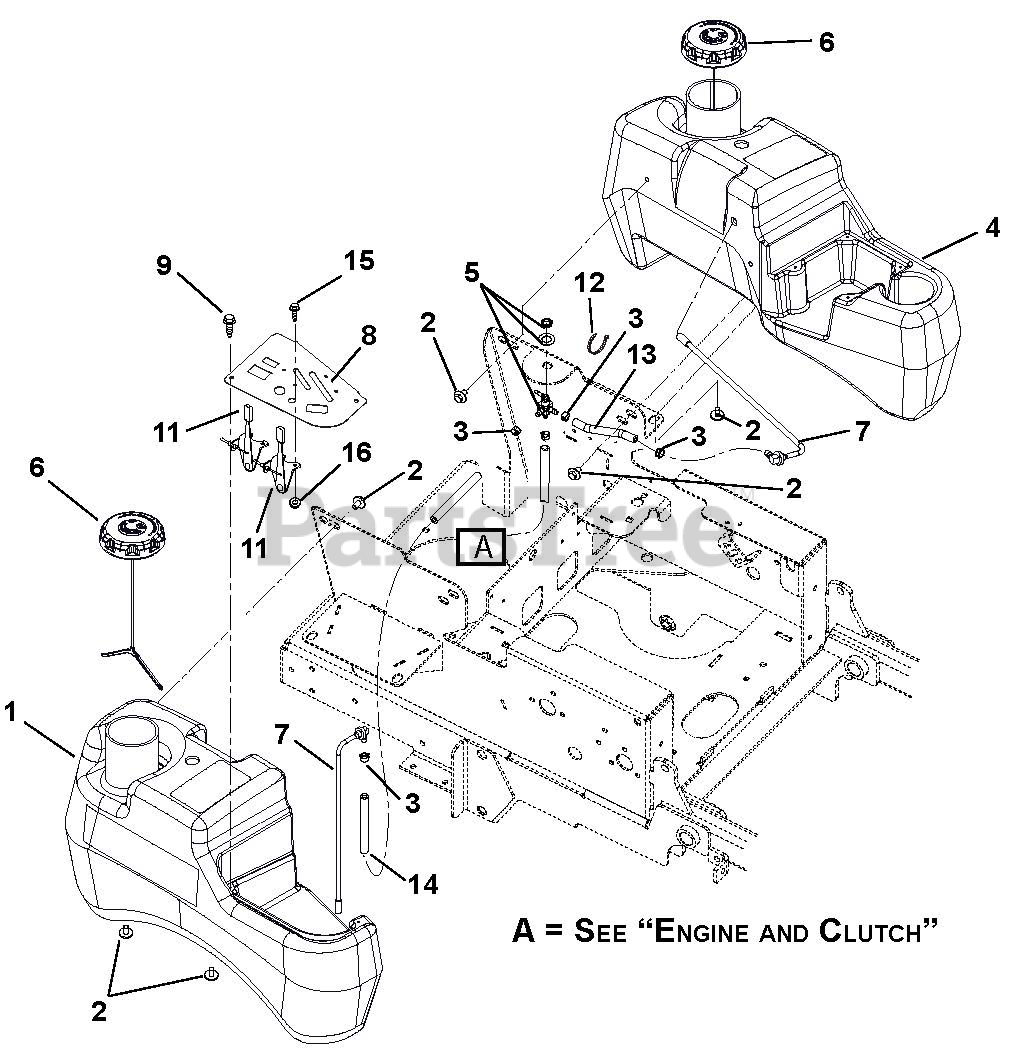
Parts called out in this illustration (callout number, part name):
1	Tank, Fuel Right Hand
2	Bolt, SEMS .31-18 x .62
3	Clamp, Fuel Line
4	Tank, Fuel Left Hand
5	Valve, Fuel
6	Cap, Fuel Vent-In Autolock
7	Assembly, Tank Fuel Pick-up
8	Panel, Control
9	Screw, Machine 10-24 x .50 Stainless
11	Cable, Control
12	Cable Tie
13	Hose, .25 Low-PERM Bulk Gas
14	Hose, .25 Low-PERM Bulk Gas
15	Screw, Machine 10-24 x .50 Hex Washer Head
16	Nut, Locking-Nylon 10-24 with Insert
